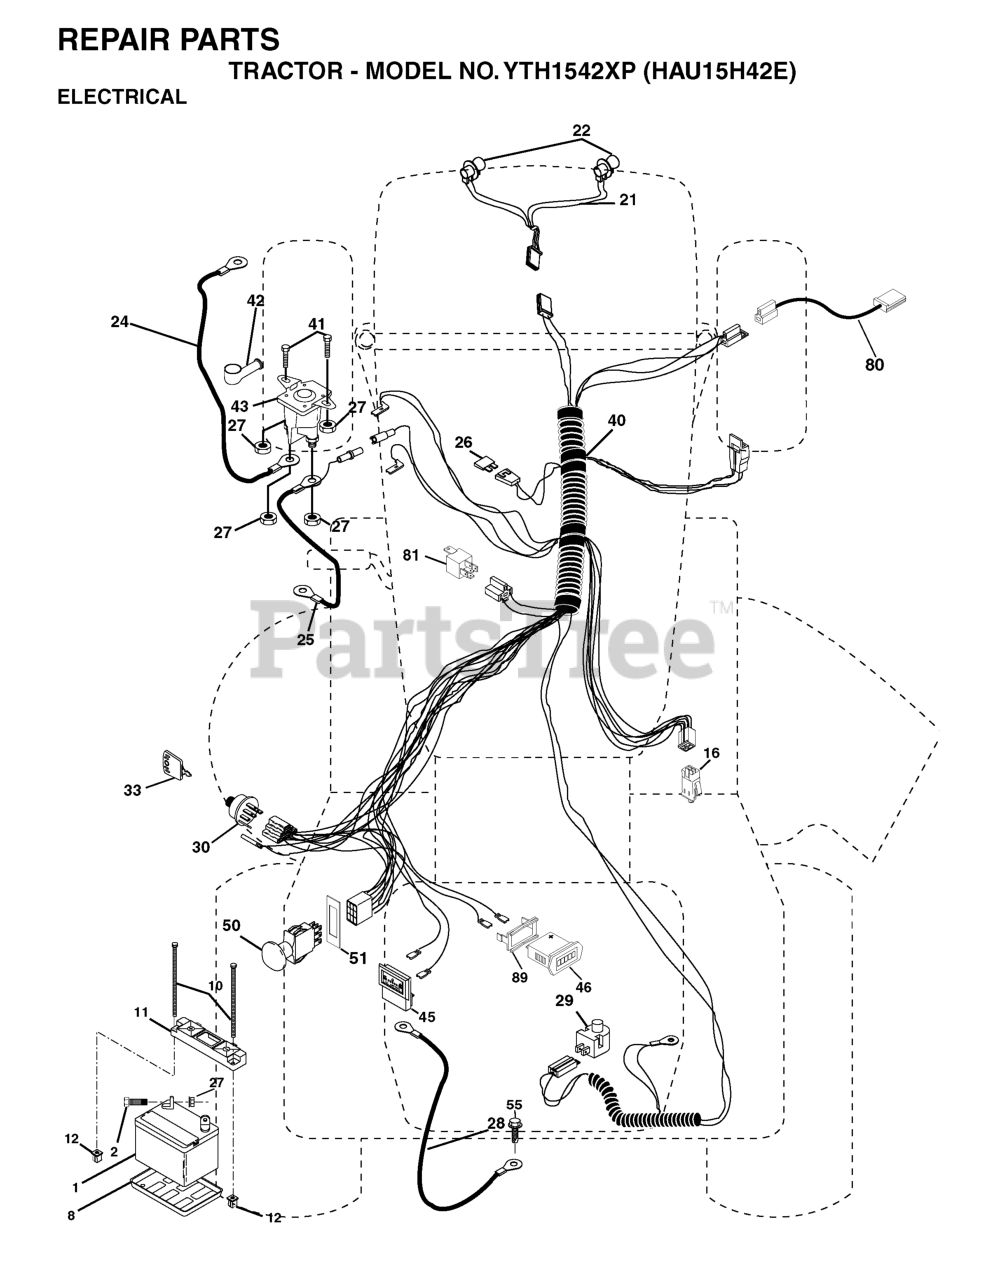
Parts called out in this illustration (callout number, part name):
1	BATTERY 12V .35 AMP
2	BOLT.HEX.1/4.X.3/4.DICHROMATE
8	BATTERY TRAY T
10	BOLT 1/4-20 X 7.5
11	BATTERY HOLDDOWN FRONT MOUNT
12	NUT, PUSH NYLON 1/4" BATTERY
16	SWITCH INTERLOOK PUSH-IN
21	HARNESS.ASM.LIGHT WSL
24	CABLE BATTERY 6 GA 22" W/16W
25	BATTERY CABLE GT
26	FUSE 20AMP
27	NUT
28	CABLE GROUND 6 GA 21" 90T BLK
29	PLUNGER SWITCH (COLOR:OLIVE)
30	IGNITION SWITCH
33	KEY MLD GEN DELTA
40	HARNESS IGN.
41	BOLT
42	TERMINAL COVER
43	SOLENOID
46	HOUR METER
50	RP.PTO.SWITCH.8 TERMINAL.BLACK
51	FRAME RETAINING RING
55	Screw 5/16-18 x 1/2 Hex, Self Tapping 5/16-18 x 1/2
80	HARNESS, CLUTCH
81	RELAY.ASSY.T
89	BRACKET SNAP-IN HOURMETER
